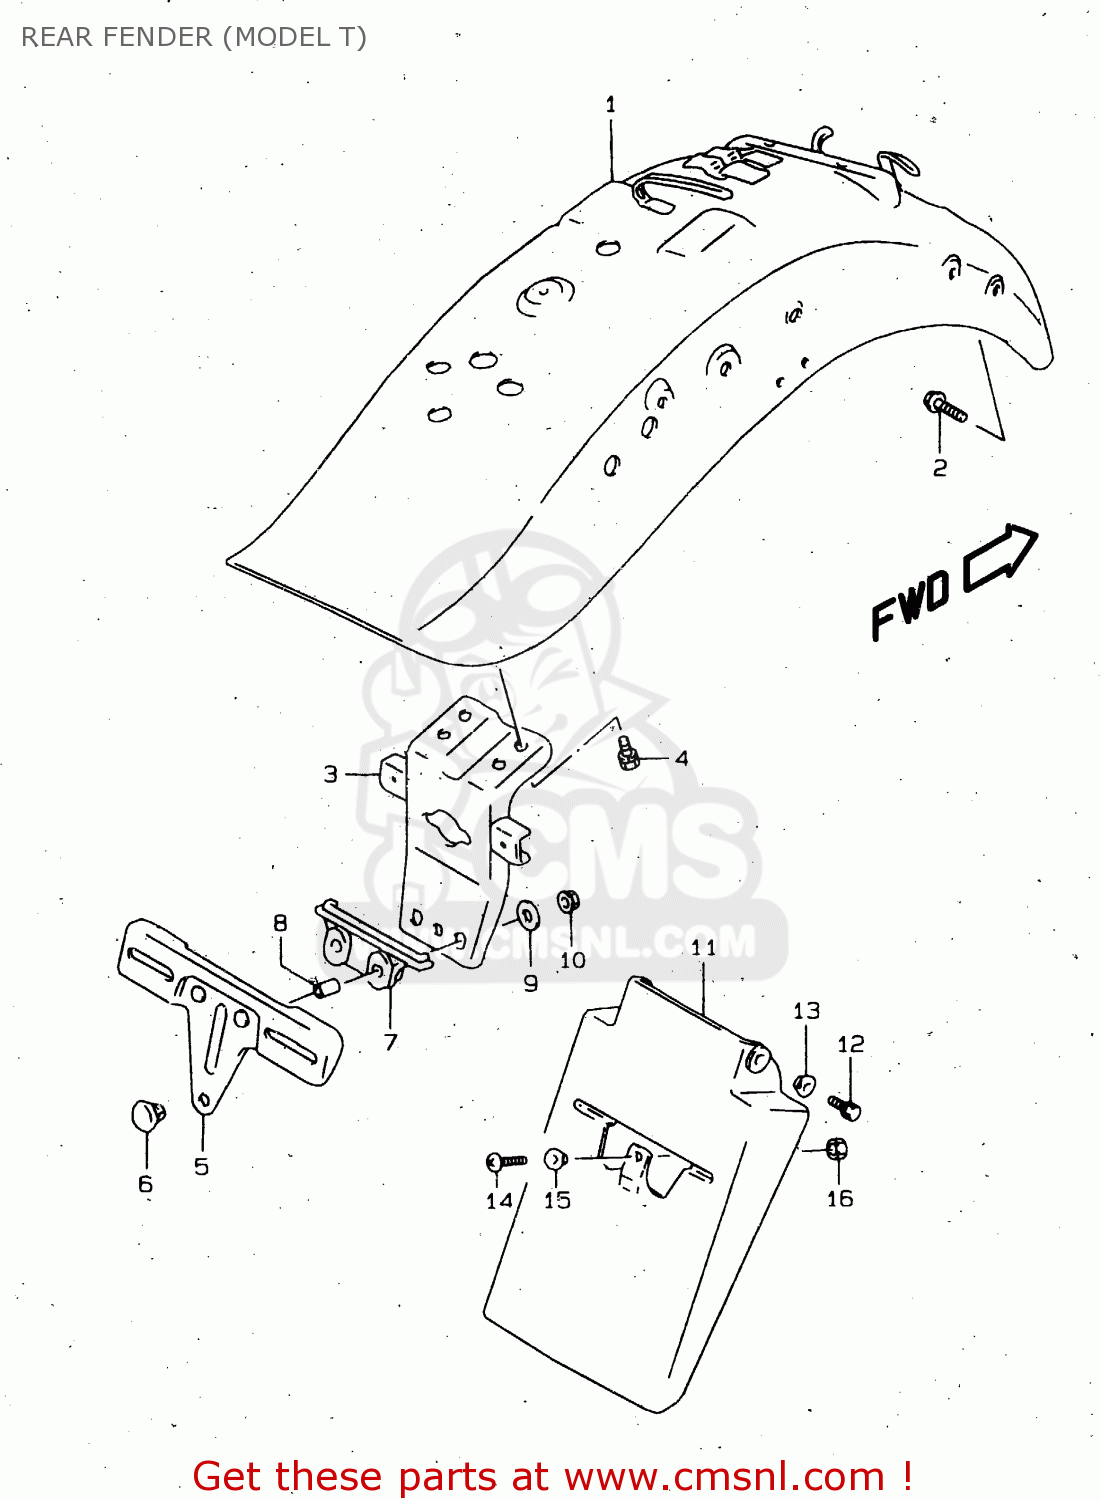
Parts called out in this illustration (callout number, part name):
1	FENDER,RR
2	BOLT
3	BRACKET,LICENSE LAMP
4	BOLT
5	PLATE,REAR LICENSE
6	CUSHION
7	CUSHION,RR LICENSE PLATE
8	SPACER (5.5X7.5X14.3)
9	WASHER(5.5X20X1.2)
10	NUT
11	EXTENSION,RR FENDER
12	BOLT
13	WASHER
14	SCREW
15	WASHER
16	NUT 6MM
